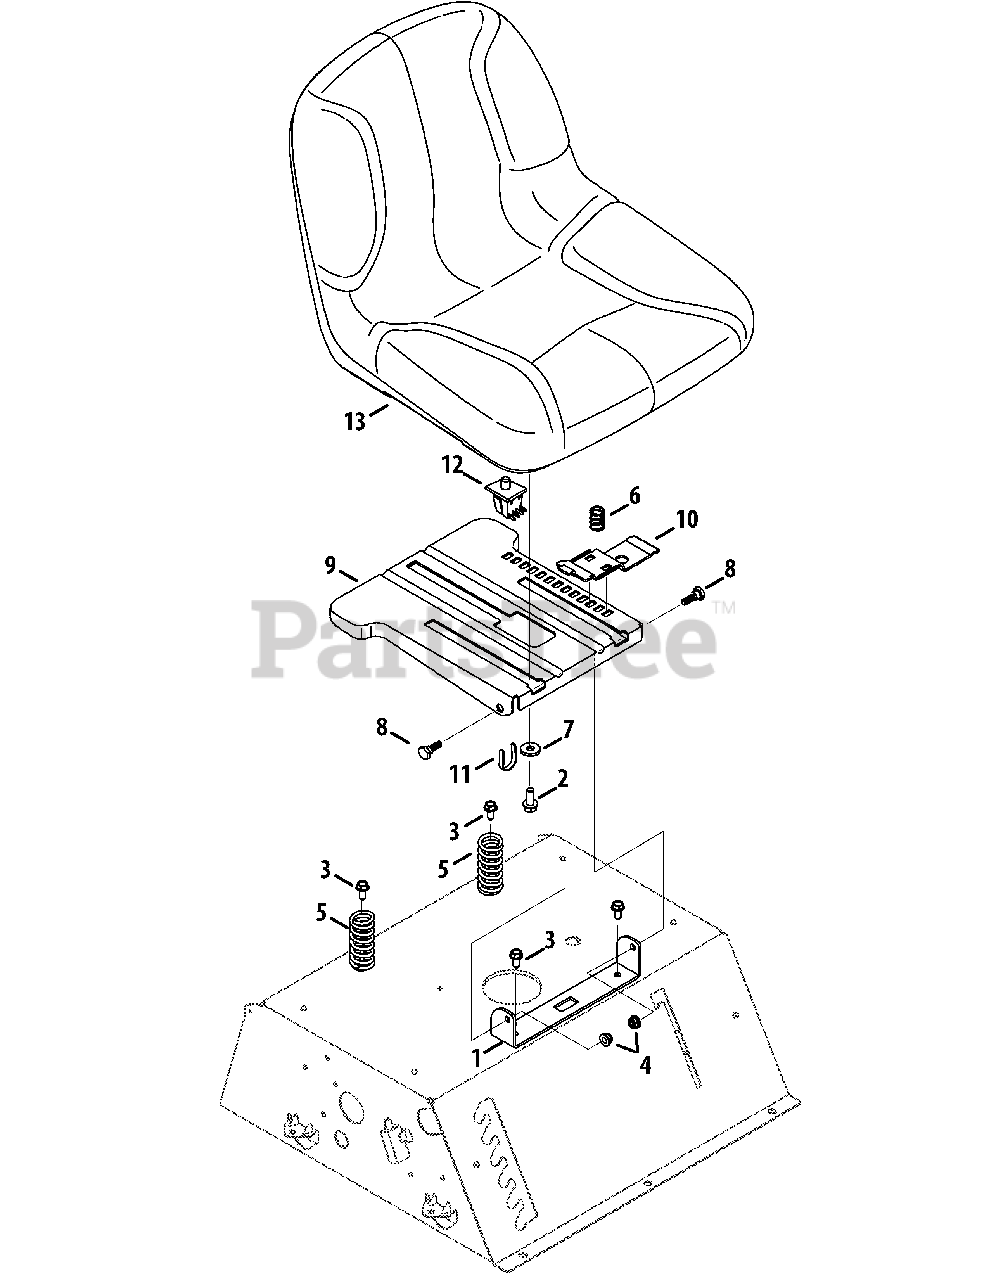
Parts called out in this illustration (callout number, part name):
1	Seat Bracket
2	Hex Flange Bolt, 3/8-16 x .875
3	Hex Washer Screw, 5/16-18 x .750
4	Flange Lock Nut, 5/16-18
5	Compression Spring
6	Compression Spring, Seat Adjustment
7	Flat Washer, .385 x 1.0 x .135
8	Shoulder Screw, .437 x .268 x 5/16-18
9	Seat Mount Bracket
10	Seat Adjustment Lever
12	Seat Switch
13	High Back Seat
